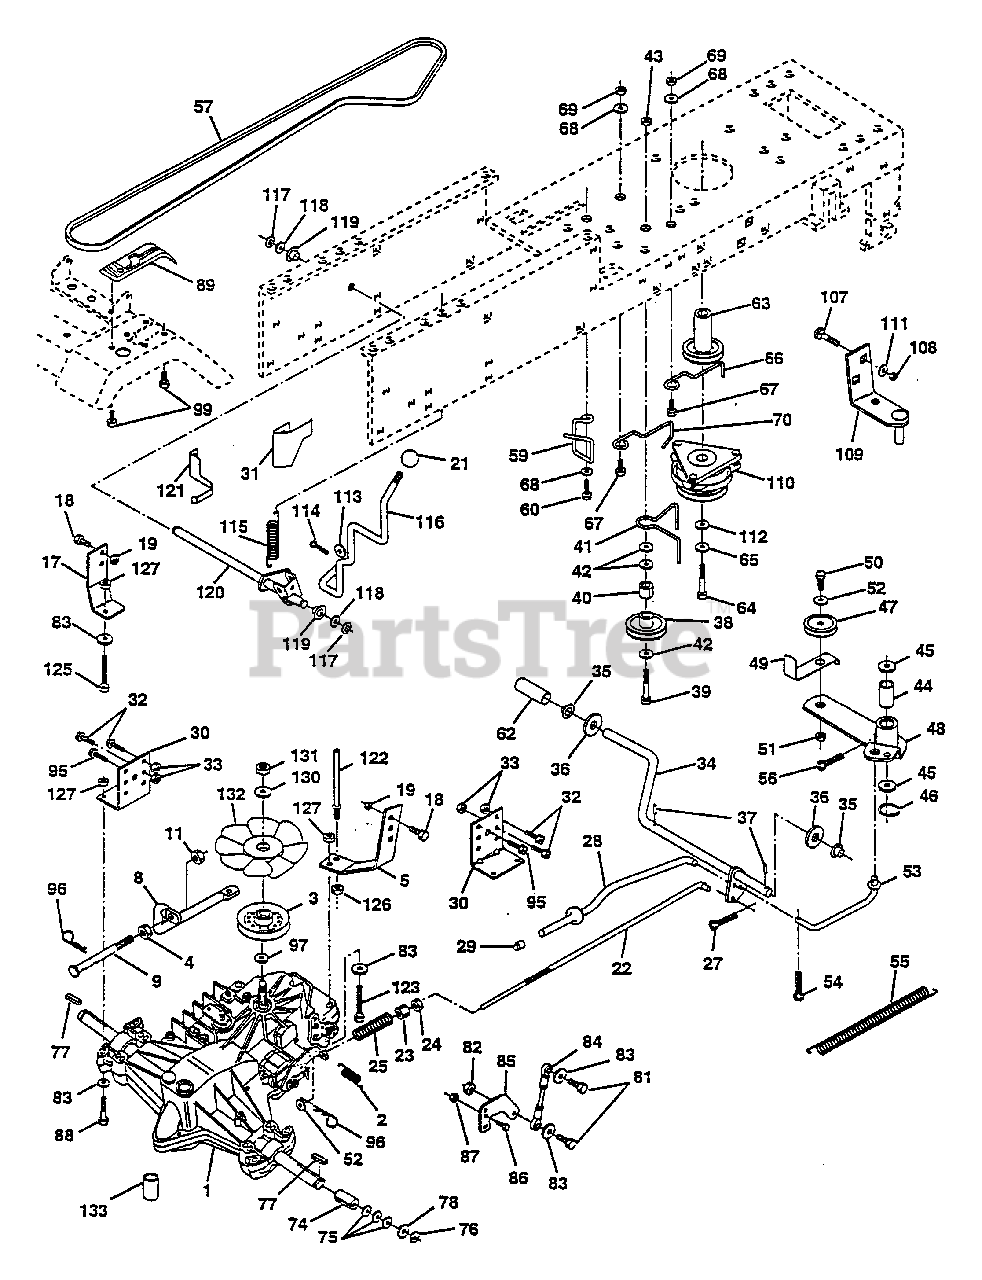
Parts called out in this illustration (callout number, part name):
1	Transaxle Assembly
2	Spring, Return, Brake
3	Pulley, Transaxle
4	Nut Hex Jam 5/16-18 Unc
5	Strap Torque Rh Hydro 18/20"T
8	Control Bypass Hydro 20" Tires
9	Rod Bypass Hydro 18/20"
11	Nut Lock Hex W/Ins 5/16-18 Unc P
17	Strap Torque Lh Hydro 18/20" T
18	Bolt Fin Hex 3/8-16 Unc x 1 Gr.5
19	Nut Lock Hex W/Wsh 3/8-16 Unc
21	Knob, Duckhead 1/2-13
22	Rod, Brake Hydro
23	Nut
24	Locknut
25	Spring, Brake Rod
27	Pin Cotter 1/8 x 3/4 CAD.
28	Rod, Parking Brake
29	Cap,Parking Brake
30	Bracket, Transaxle
31	Keeper Belt Lh
32	Bolt Hex Hd 5/16-18 Unc x 3/4
33	Nut Lock Hex W/lns. 5/16-18 Unc
34	Shaft, Foot Pedal
35	Bearing, Nylon
36	Washer
37	Pin, Roll
38	Pulley, Idler, Flat
40	Spacer Split
41	Keeper, Belt Retainer
42	Washer 13/32 x 13/16 x 12 Gauge
43	Nut
44	Bearing, Nylon
45	Washer, Hardened
46	Ring, Klip
47	Pulley, Idler, V-Groove
48	Bellcrank Assembly
49	Retainer, Belt
50	Bolt
52	Washer
53	Link, Clutch
54	Pin
55	Spring, Return, Clutch
56	Pin
57	V-Belt, Ground Drive
59	Keeper, Center Span
60	Screw Thdrol. 3/8-16 x 3/4 Ty. TT
62	Cover, Pedal
63	Pulley, Engine
64	Bolt, Hex
65	Washer
66	Keeper Belt Engine
67	Bolt
68	Washer 13/32 x 13/16 x 12 Gauge
70	Keeper Belt Engine
73	Nut Crownlock 3/8-16
75	Washer 25/32 x 1-1/4 x 16 Gauge
77	Key, Square
78	Washer 25/32 x 1-5/8 x 16 Gauge
81	Bolt Fin Hex 5/16-18 Unc x 1-1/4
82	Nut Lock Hex W/Ins. 5/16-18 Unc P
83	Washer 11/32 x 3/4 x 16 Ga.
84	Rod, Tie Hydro 20° Tires
85	Arm, Control Hydro
86	Screw Cap Hex 5/16 x 18 x 1
87	Nut Lock Hex W/Ins. 5/16-18 Unc P
88	Bolt Fin Hex 5/16-18 Unc
89	Console, Shift
95	Screw, Thdroll. 3/8-16 x 1 Type TT
96	Retainer Spring 1" Znc/Cad
97	Washer 21/32 x 1 x 16 Ga.
99	Screw
113	Washer 17/32 x 3/4 x 16 Ga.
114	Pin Cotter 1/8 x 1 CAD
115	Spring Torsion T/A
116	Rod Shift Hydro LT
117	Ring Klip #5304-62
118	Washer 21/32 x 1-1/4 x 16 Ga.
119	Bushing Rod Strig. 629/632 ID
120	Shaft Asm. Cross Hydro 20" Tires
121	Keeper Belt Lh Hydro 0750.18/
122	Keeper Belt Rh Hydro 0750.18/
123	Bolt Fin Hex 5/16-18 x 2-1/4
125	Bolt Fin Hex 5/16-18 Unc x 1-1/2
126	Nut Keps Hex 3/8-16 Unc
127	Nut Lock Hex W/Ins 5/16-18 Unc P
130	Washer Belleville .501D x 1.50D
131	Nut Nylon Insert 1/2-20 Unf
132	Fan, Hydro 7"
133	Line Fuel Hydro 4"
